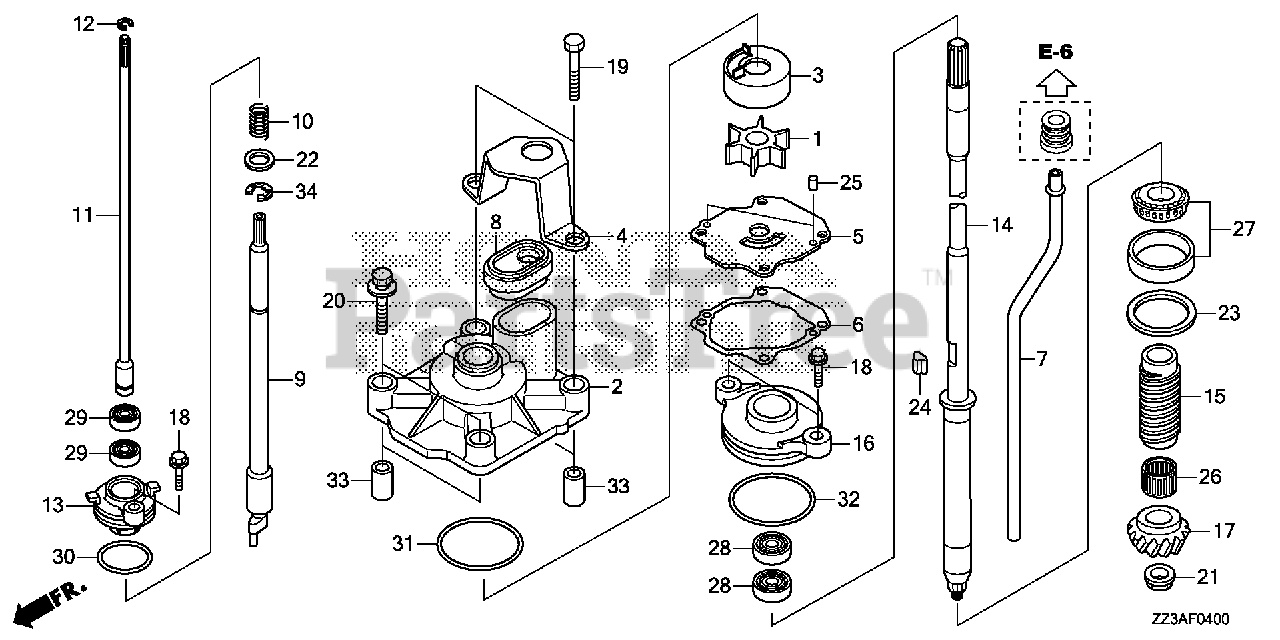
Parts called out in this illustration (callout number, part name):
1	IMPELLER, PUMP
2	HOUSING, IMPELLER
3	LINER, PUMP
4	HOLDER, WATER TUBE SEAL
5	COVER, IMPELLER
6	GASKET, IMPELLER
7	TUBE, WATER (XL)
8	RUBBER, WATER TUBE SEAL
9	ROD, SHIFT
10	SPRING, SHIFT ROD
11	ROD A, SHIFT (XL)
12	RING, STOPPER
13	HOLDER, SHIFT ROD
14	SHAFT, VERTICAL (XL)
15	SLINGER, OIL
16	HOUSING, WATER SEAL
17	GEAR, PINION (14T)
18	BOLT, FLANGE (6X20)
19	BOLT, HEX. (8X40)
20	BOLT-WASHER (8X40)
21	NUT, SPECIAL (12MM)
22	WASHER, PLAIN (12MM)
23	SHIM, GEAR (40X46X0.10) (A)
23	SHIM, GEAR (40X46X0.15) (B)
23	SHIM, GEAR (40X46X0.30) (C)
23	SHIM, GEAR (40X46X0.50) (D)
24	KEY, WOODRUFF
25	PIN, DOWEL (6X10)
26	BEARING, NEEDLE (7/8X11/8X1)
27	BEARING (25X47X15)
28	SEAL, WATER (17X36X6)
29	SEAL, WATER (12X21X6)
30	O-RING (33.7X3.5)
31	O-RING, WATER PUMP
32	O-RING (58.5X3.5)
33	COLLAR, DISTANCE
34	E-RING (10MM)
